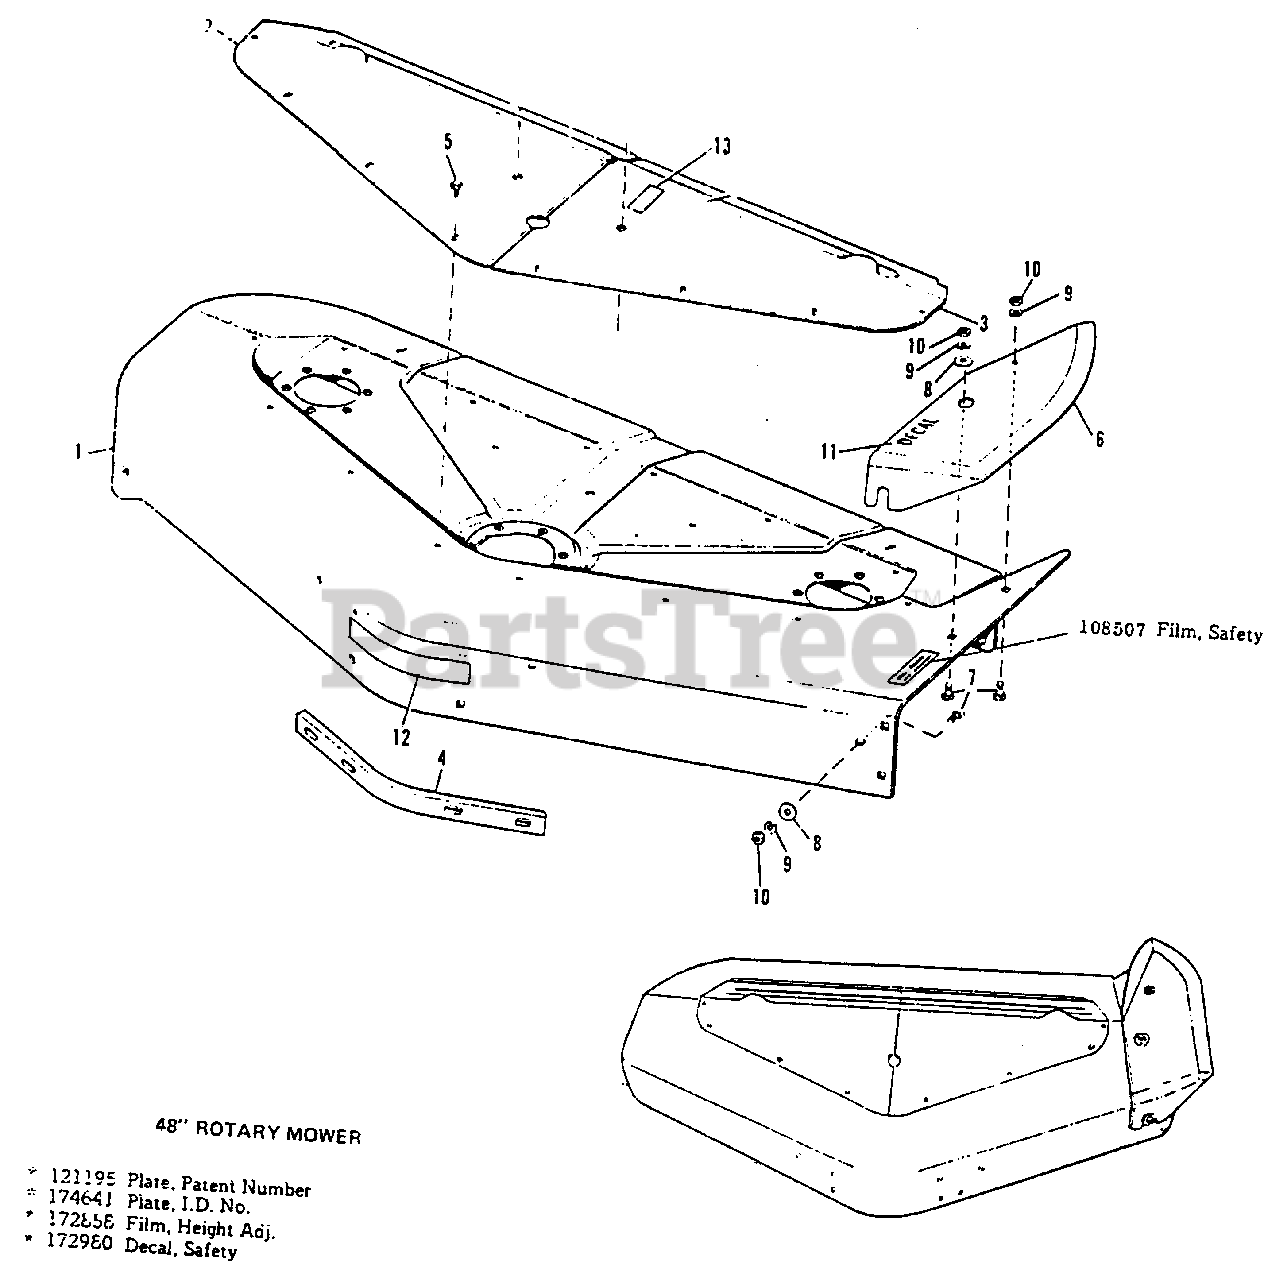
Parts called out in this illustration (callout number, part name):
1	Mower Housing
2	R.H. Cover
3	L.H. Cover
4	Reinforcing Bar
5	Self Tapping Screw, 1/4"-20 x 3/8"
6	Deflector
7	Carriage Bolt, 3/8"-16 x 3/4"
8	Special Washer
9	Lock Washer
10	Hex. Nut, 3/8"-16
11	Decal, Safety
12	Film Simplicity
13	Film-Belt Installation
